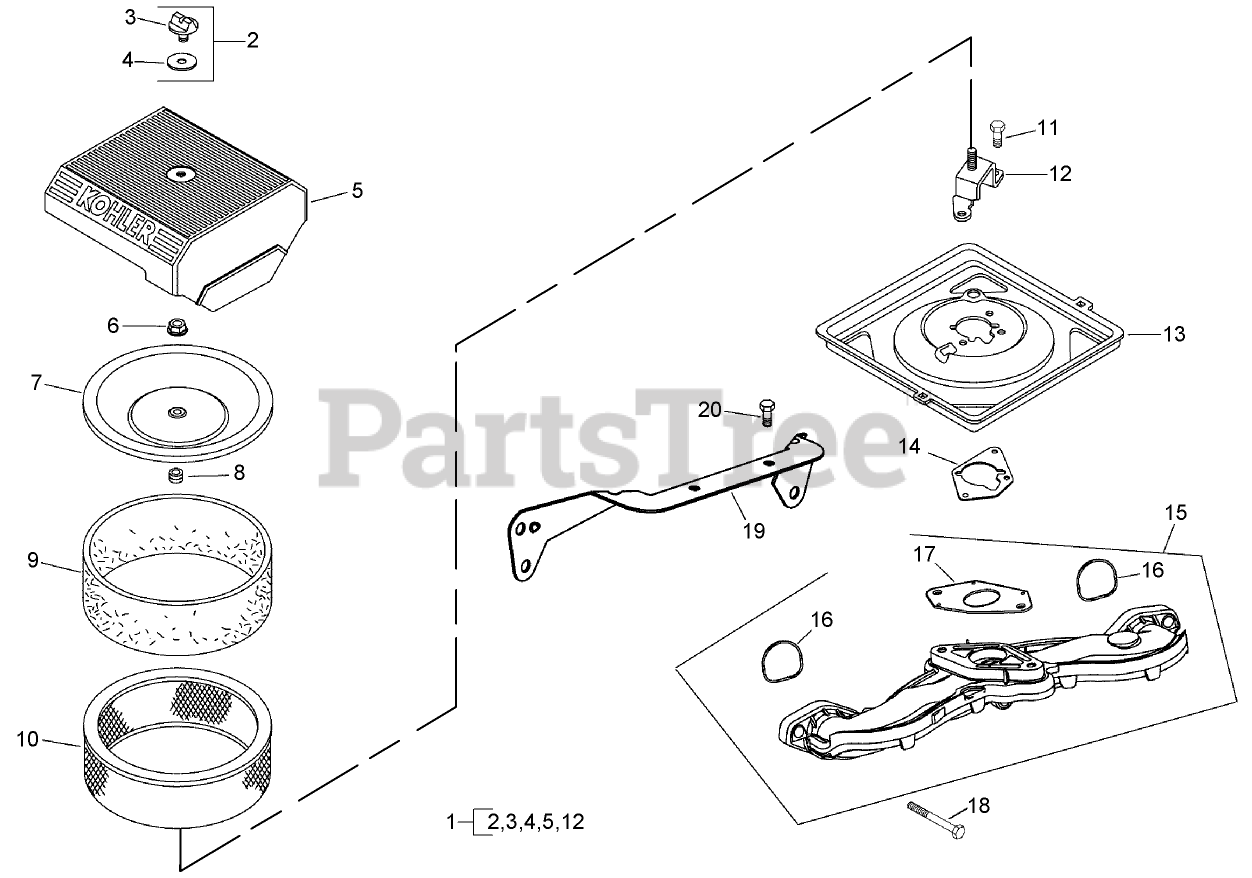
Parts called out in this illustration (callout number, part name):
1	Air Cleaner Cover Kit (Includes 2-5, 12)
2	Knob Kit (Includes 3, 4)
3	KNOB-COVER
4	O-RING
5	Cover-Cleaner, Air
6	NUT-FLANGE (M6X1.0)
7	COVER-AIR CLEANER, INNER
8	Seal
9	PRE-CLEANER
10	ELEMENT-FILTER, AIR
11	SCREW-FLANGE, THREAD FORMING (M6X1.0X16)
12	Bracket-Base, Air Cleaner
13	BASE-CLEANER, AIR
14	GASKET-BASE, AIR CLEANER
15	Intake Manifold ASM (Includes 16, 17)
16	O-Ring (intake port)
17	Gasket-Carburetor
18	SCREW-FLANGE (M6X1.0X40)
19	BRACKET-BASE, AIR CLEANER
20	SCREW-HHFTF (M5X.80X10)
